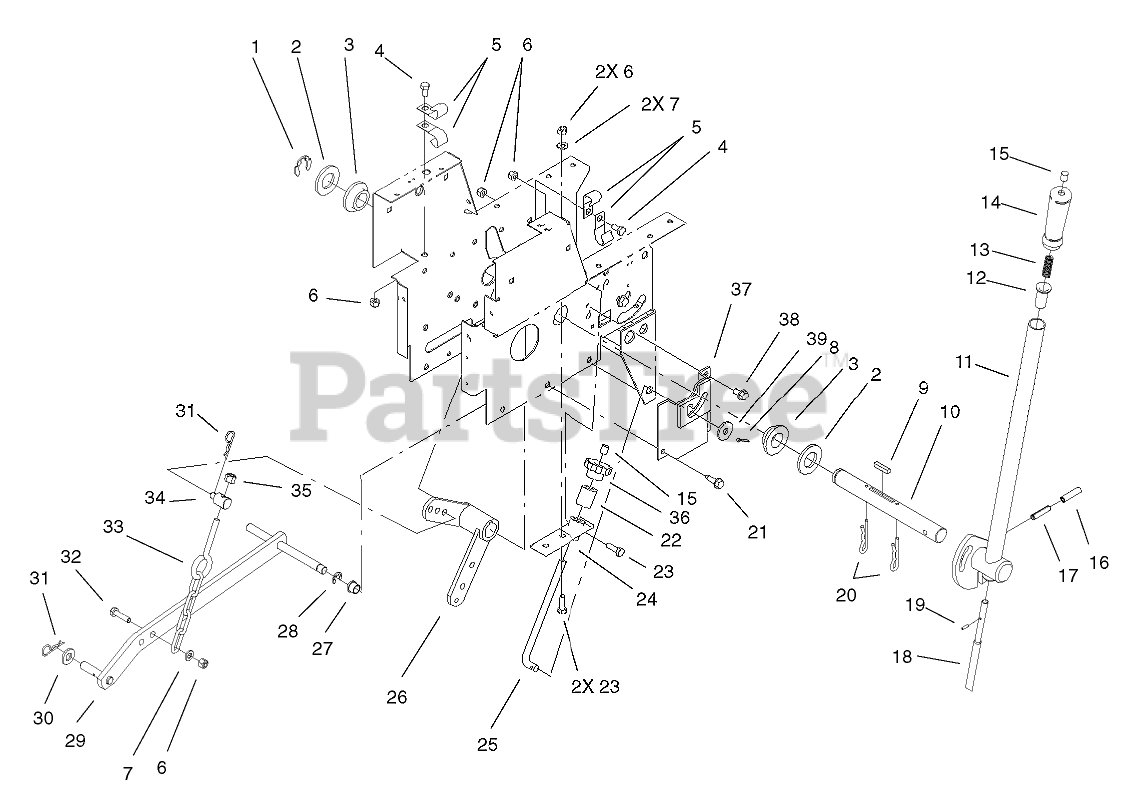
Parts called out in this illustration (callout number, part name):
1	RING-RETAINING
2	WASHER-FLAT
3	BEARING-FLANGE
4	SCREW-HH
5	CLIP
6	NUT-LOCK, NI
7	WASHER-PLAIN
8	PIN-COTTER
9	KEY-SQUARE
10	SHAFT-LIFT LEVER
11	LIFT HANDLE ASM
12	RETAINER-SPRING
13	SPRING-COMPRESSION
14	GRIP-HANDLE
15	CAP-ROD, PLUNGER
16	PIN-SPRING
17	PIN-ROLL
18	ROD-LATCH LIFT
19	PIN-SPIROL
20	PIN-HAIR
21	SCREW-TAPTITE
22	SLEV-LIFT ADJS
23	SCREW-HH
24	CASTING-LIFT LEVER
25	ROD-HEIGHT CONTROL
26	LIFT LEVER ASM
27	BUSHING
28	RING-RETAINING, EXTERNAL
29	LIFT BAR ASM
30	WASHER-FLAT
31	PIN-HAIR
32	SCREW-HH
33	CHAIN-LIFT
34	TRUNNION-LIFT
35	NUT-LOCK, NI
36	KNOB-LIFT CONTROL
37	LIFT LEVER ASM
38	SCREW-HWHTF
39	WASHER
